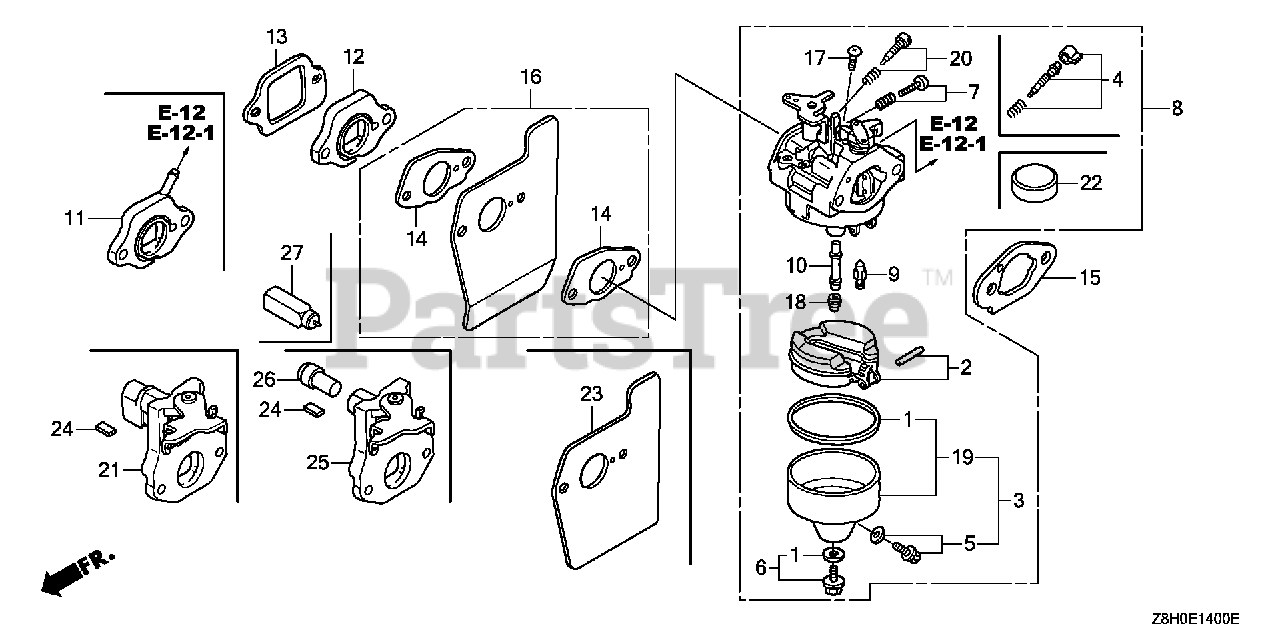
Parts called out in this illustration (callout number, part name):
1	GASKET SET
3	CHAMBER SET, FLOAT (CARBURETOR NO.)
4	SCREW SET (CARBURETOR NO.)
5	SCREW SET, DRAIN (CARBURETOR NO.)
6	SCREW SET
7	SCREW SET (THROTTLE STOP) (CARBURETOR NO.)
8	CARBURETOR ASSY. (BB64G D)
9	VALVE, FLOAT (CARBURETOR NO.)
10	NOZZLE, MAIN
11	INSULATOR, CARBURETOR
13	GASKET, INSULATOR
14	GASKET, CARBURETOR
15	GASKET, CARBURETOR
16	GUIDE, AIR
17	SCREW, PAN (5X6)
18	JET, MAIN (#58)
18	JET, MAIN (#60) (CARBURETOR NO.)
18	JET, MAIN (#62) (CARBURETOR NO.)
